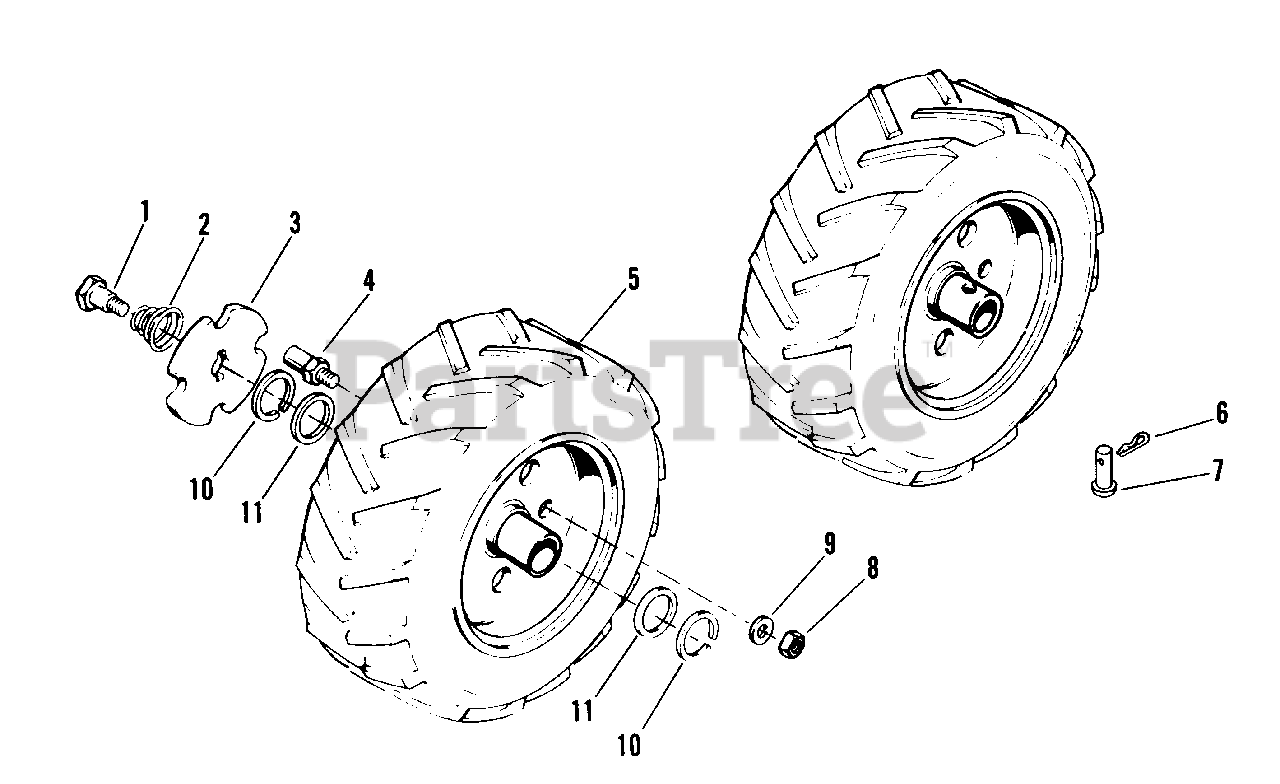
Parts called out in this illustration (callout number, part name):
1	BOLT, Shoulder
5	WHEEL & TIRE ASSY.
6	PIN, Quick
7	PIN
8	LOCKNUT, Hex, 3/8-16
9	WASHER, Plain, 5/16
10	RING, Retaining
11	WASHER, Special
